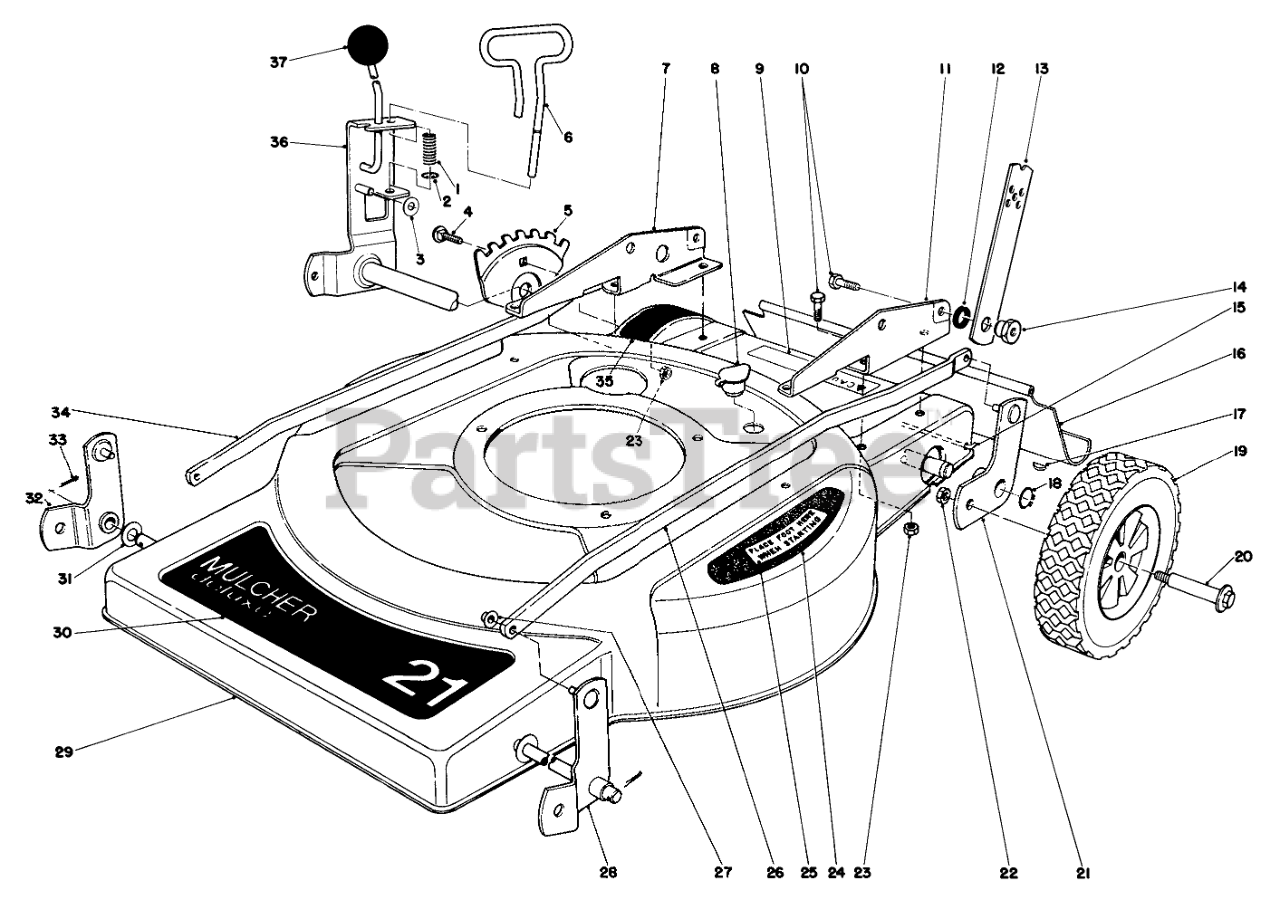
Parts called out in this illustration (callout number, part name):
1	SPRING-COMPRESSION
2	E-RING
3	WASHER-FLAT
4	Carriage Bolt
5	HOC ADJUSTMENT PLT
6	STOP ROD
7	Bracket Handle R.H.
8	WASHOUT PLUG
9	Caution Decal
10	SCREW-HH
11	Bracket-Handle R.H.
12	SPACER
13	HANDLE LATCH
14	HANDLE PIVOT NUT
15	SHIELD ROD
16	SHIELD - TRAILING
17	KEY-WOODRUFF
18	RING-RETAINING
19	WHEEL TIRE ASM 8 IN
20	BOLT-WHEEL
21	Pivot Arm
22	Nut
23	NUT-LOCK, CONE
24	PAD STEP
25	Decal Step Pad
26	Spanner Link L.H.
27	NUT-SPEED
28	LH FRT PIVOT ARM WA
29	Housing
30	Decal-Front Deck
31	WASHER
32	Pivot Arm
33	PIN-COTTER
34	Spanner Link R.H.
35	Decal Height of Cut
36	Pivot Arm Bracket
